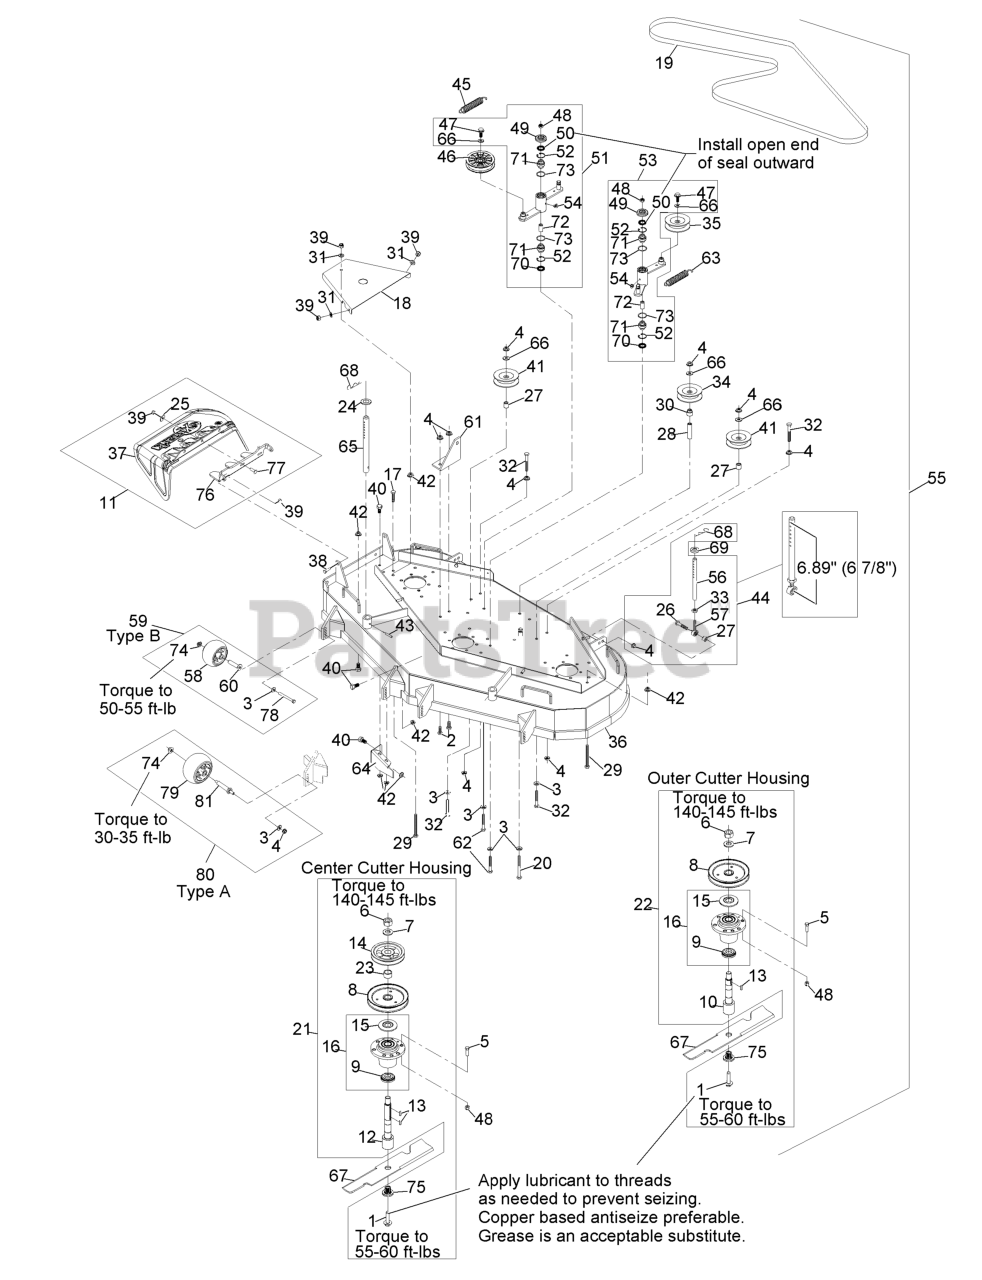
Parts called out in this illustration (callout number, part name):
1	SCREW,SEMS 1/2-20 X 2.19
2	SCREW-HH
3	WASHER-BELLEVILLE
4	NUT-HHF, WHIZ
5	SCREW-HH
8	SHEAVE,BLADE DRIVE 6.30
9	SPACER-GUARD, BOTTOM
10	KIT, SPLINED SPINDLE 103-
11	ASM,FMD DISCHARGE CHUTE
12	KIT, SPLINED SPINDLE 103-
14	SHEAVE,MOWER DRIVE
15	GUARD-BEARING, TOP
16	KIT, CUTTER HOUSING
17	SCREW-HH
18	SHIELD,BELT SIDE FMD524
19	BELT,BLADE DRIVE FMD524
20	SCREW-HH
21	ASM,CUTTER HSG FMD524 CTR
22	ASM, CUTTER HSG COMPLETE
23	SPACER,TUBE
24	SPACER-DECK SUPPORT
25	WASHER-FLAT
26	SCREW-HH
28	SPACER-ANCHOR, CLUTCH
29	BOLT,TAP HH
30	BUSHING,IDLER
31	WASHER-FLAT
32	BOLT-CARR
33	NUT-HJ
34	PULLEY-IDLER
35	PULLEY-IDLER
36	ASM, DECK W/ DECALS FMD52
37	CHUTE,DISCHARGE
38	SCREW-HH
39	NUT-LOCK, NI
40	SCREW-HH
41	IDLER,PULLEY
44	KIT,SUPPORT LINK W/PIN
45	SPRING-EXTENSION
46	PULLEY-IDLER, FLAT
47	SCREW-HHF
48	NUT-LOCK, NI
49	GUARD-TOP
50	SEAL-LIP, SINGLE
51	KIT, IDLER ARM W/BEARINGS
52	RING-SNAP
53	KIT, IDLER ARM W/BEARINGS
54	FITTING-GREASE, 90 DEG
55	Asm, Complete Deck
56	LINK,SUPPORT
57	BALLJOINT
58	ROLLER-SCALP, ANTI
59	KIT, ANTI-SCALP ROLLER
60	AXLE, ROLLER
61	BRACKET,SPRING ANCHOR
62	SCREW-HH
63	SPRING-EXTENSION
64	BAFFLE,DISCHARGE
65	ROD,DECK SUPPORT
66	WASHER-FLAT
68	PIN,HAIR COTTER
70	SEAL-LIP, DOUBLE
71	BEARING-SPHERICAL
72	BUSHING-LEVER, LIFT
74	Nut-Nyloc 3/8-16 Flg
75	BUSHING,SPLINED
76	BRACKET, DISCHARGE CHUTE
77	SCREW-CARR
78	SCREW-HH 3/8-16 X 3 3/4 GR 8
79	ROLLER-SCALP, ANTI
